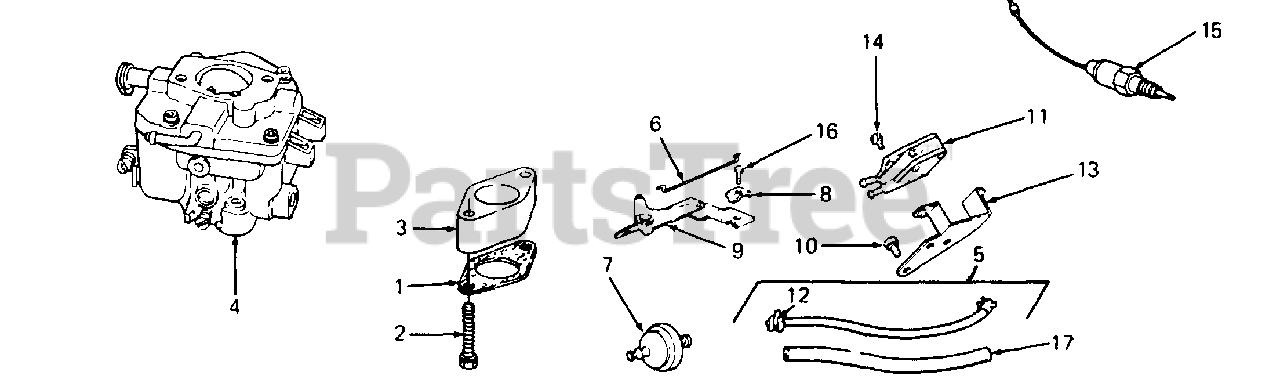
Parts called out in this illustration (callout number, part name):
1	Gasket, Carburetor Mtg
2	Screw, Sems
3	Spacer, Carburetor
4	Carburetor Assy
5	Line, Fuel
6	Link, Choke
7	Filter, Fuel
8	Clamp, Casing
9	Bracket, Choke
10	Screw, Sems
11	Pump, Fuel
12	Clamp, Fuel Line
13	Bracket, Fuel Pump
14	Screw, Mtg
15	Solenoid
16	Screw, Hex Hd
17	Insulation, Fuel Line
